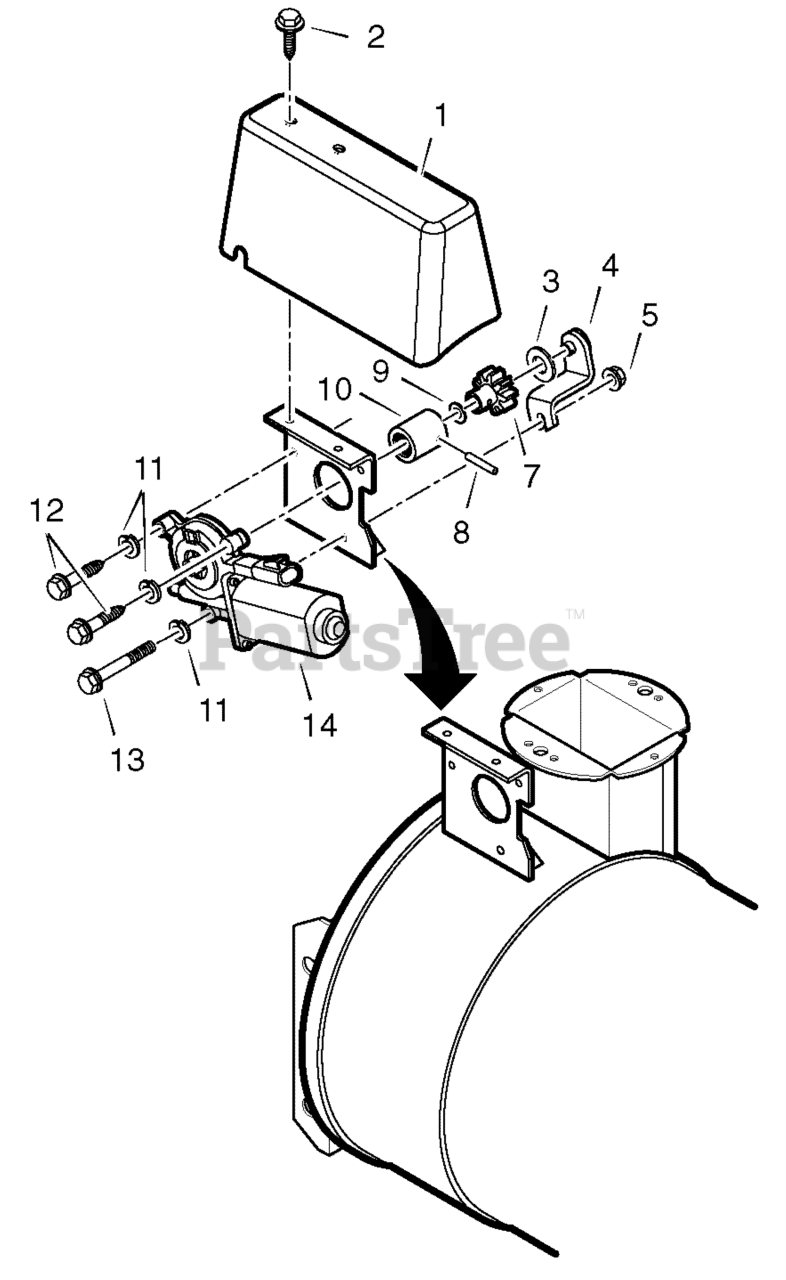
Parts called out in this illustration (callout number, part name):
1	COVER, MOTOR
2	SCREW
3	WASHER
4	BRACE, CHUTE GEAR
5	NUT
7	GEAR
8	PIN, SPRING
9	RING, RETAINER
10	ADAPTER
11	WASHER, SPLIT
13	BOLT, HEX
14	MOTOR, ELECTRIC
